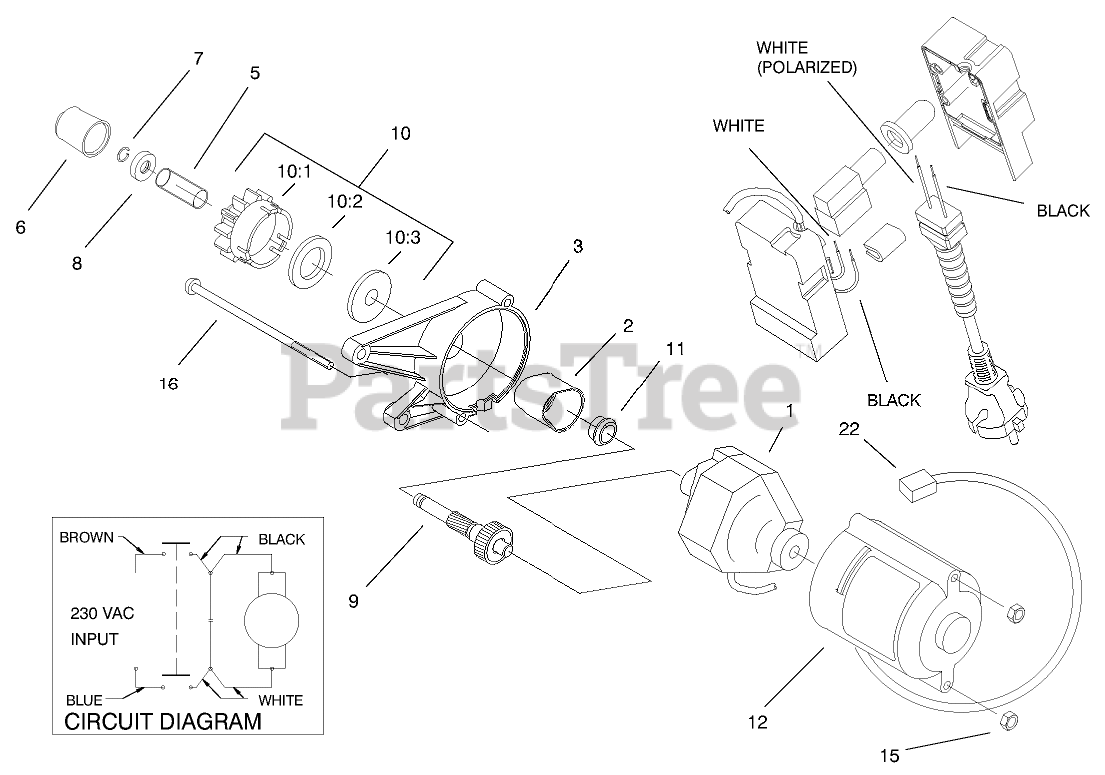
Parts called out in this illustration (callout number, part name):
1	Starter Motor ASM (only on: 38183)
2	Cover-Gear (only on: 38183)
3	Housing-Upper Starter (only on: 38183)
5	Spring (only on: 38183)
6	Pinion-Cap (only on: 38183)
7	Ring-Lock (only on: 38183)
8	Stop-Pinion (only on: 38183)
9	Shaft/Gear ASM-Service (only on: 38183)
10	Pinion ASM (R & S)(only on: 38183)
10:1	Nut (only on: 38183)
10:2	Pinion (only on: 38183)
10:3	Ring-Rubber (only on: 38183)
11	Bushing (only on: 38183)
12	Housing-Lower Starter (only on: 38183)
15	Nut-Lock Ni (only on: 38183)
16	Screw-Mach (only on: 38183)
22	Tie-Cable (only on: 38183)
